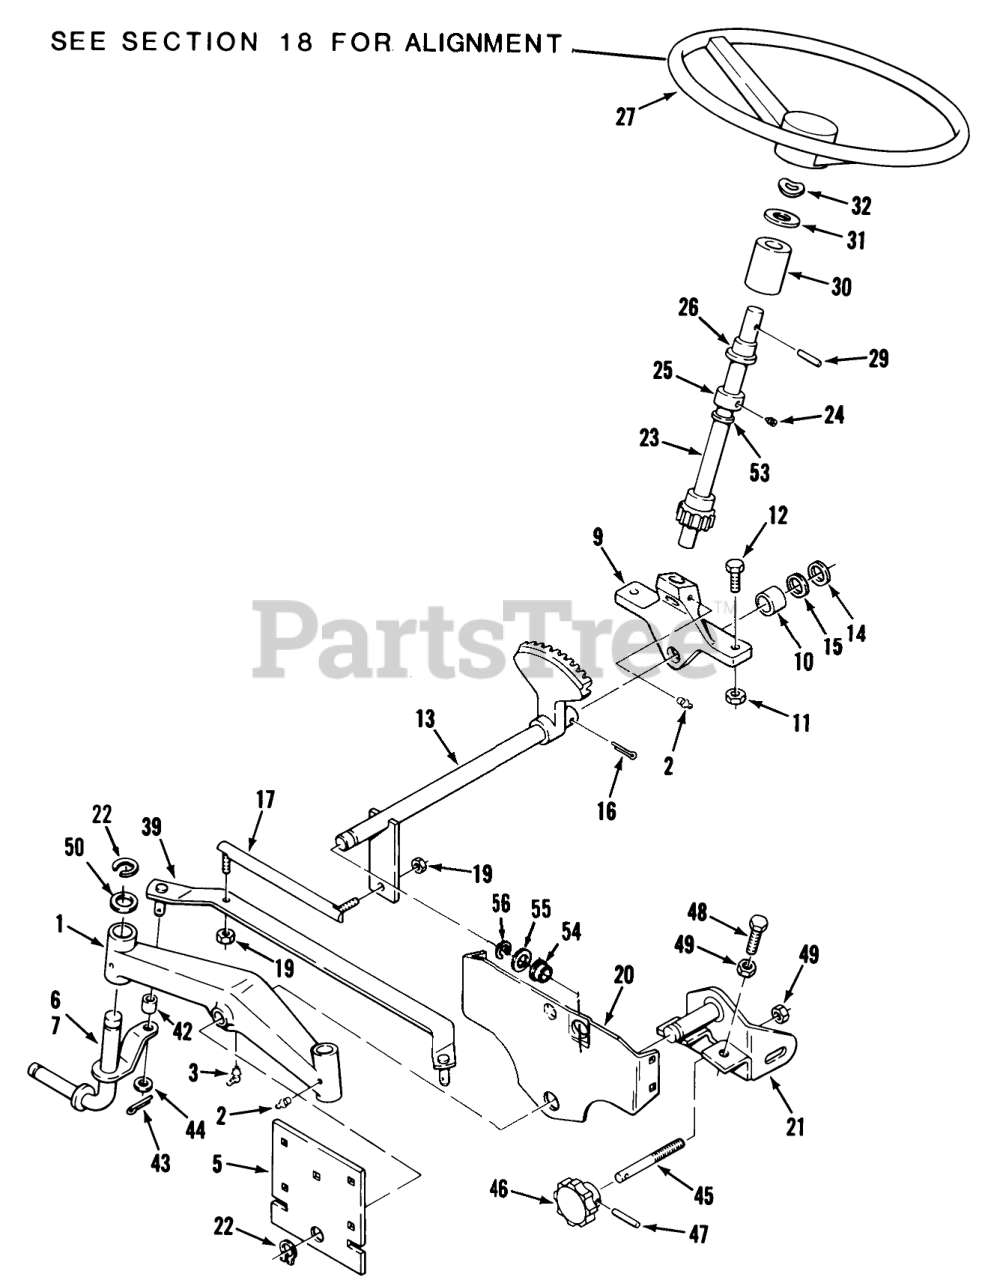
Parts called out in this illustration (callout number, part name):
1	AXLE-FRONT R
2	Zerk
3	FITTING-GREASE
5	PLATE-FRONT AXLE R
6	Front Spindle Assy RH
7	Front Spindle Assy LH
9	Support
10	BEARING-BRONZE
11	NUT
12	BOLT
13	ASSY-STRG SHAFT L B
14	WASHER-SHIM
15	WASHER
16	PIN-4
17	BALL JOINT ASSY L R
19	NUT-6
20	SUPPORT AXLE R
21	ASSY-FRT HANGER R
22	Snap Ring
23	ASSY-STRG SHFT-UP R
24	SCREW-SET
25	Collar
26	BEARING-FLANGED
27	STEERING WH 13" PLAS
27	STEERING WHEEL-15"
29	Pin-Roll
30	TUBE-STEERING
31	WASHER-FLAT
32	WASHER-BOWED
39	ASSY-TIE ROD R
42	SPACER
44	WASHER
45	ROD-ADJUSTING
46	KNOB-ADJUSTMENT
47	PIN-ROLL
48	Bolt
49	NUT-HEX, JAM
50	WASHER
53	RING-RETAINING
54	BUSHING
55	WASHER SPECIAL
56	Ring
